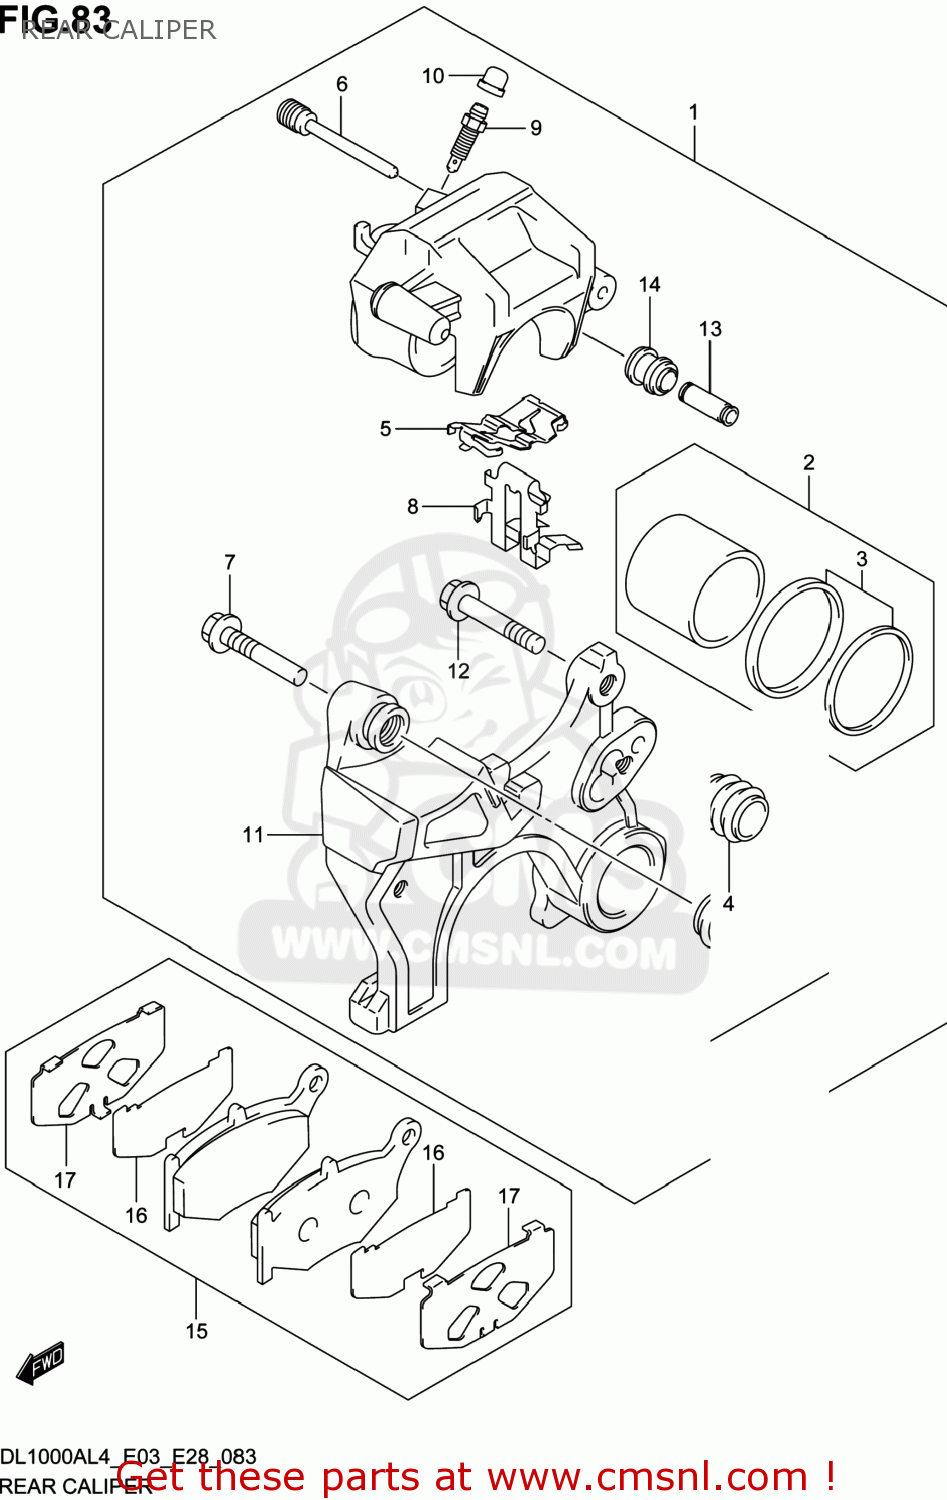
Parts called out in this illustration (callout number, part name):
1	CALIPER ASSY,RR
2	PISTON SET
3	SEAL SET,PISTON
4	BOOT,AXLE
5	SPRING,PAD
6	PIN,PAD
7	PIN,BOLT
8	RETAINER
9	BLEEDER
10	CAP,BLEEDER PLUG
11	BRACKET
12	BOLT
13	SLEEVE
14	BOOT,SLEEVE
15	PAD & SHIM SET (NAS)
16	INSULATOR
17	SHIM
